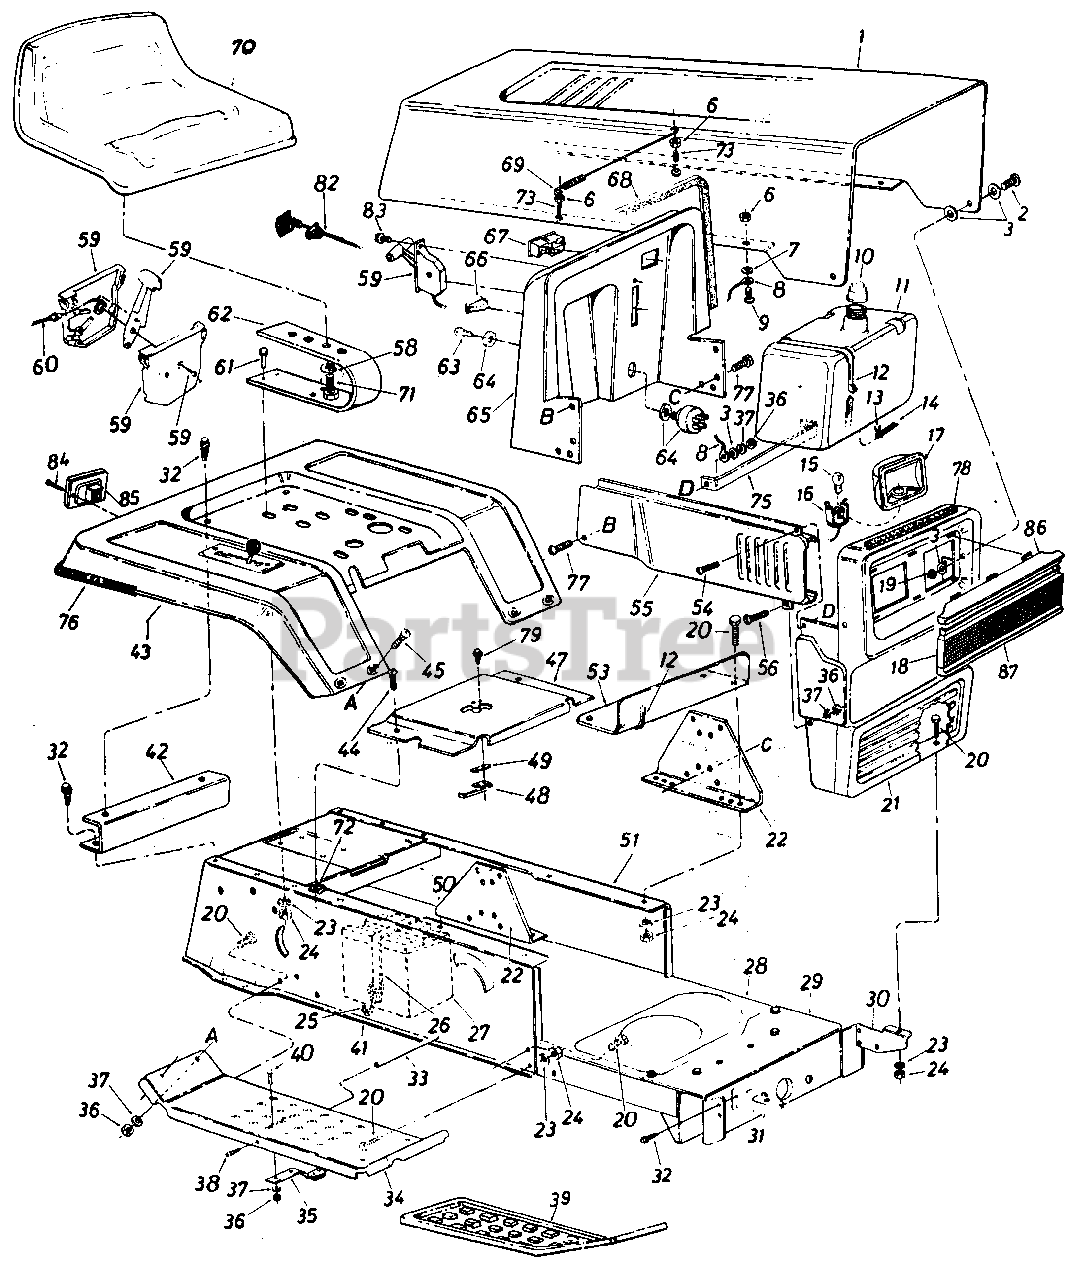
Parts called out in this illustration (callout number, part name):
1	Hood
2	Hex Scr. 1/4-20 x .62" Lg.
3	Fl-Wash. .296" I.D. x .73" O.D.
6	Hex Sems Nut #10-24 Thd.
7	Fl-Wash. .203" I.D. x .41" O.D. x .040
8	Hood Stop
9	Truss Hd. Scr. #10-24 x 1/2"
10	Fuel Cap Gauge
11	Fuel Tank
12	Tie Strap
13	Hose Clamp
14	Fuel Line
15	Lamp
16	Twist Lock Lamp Socket
17	Headlight Housing
18	Headlight Bezel
19	Hex L-Nut 1/4-20 Thd.
20	Hex Bolt 5/16-18 x .75" Lg.
23	L-Wash. 5/16" I.D.
24	Hex Nut 5/16-18 Thd.
25	Battery Strap Hook
26	Battery Hold Down Strap
27	12V Battery
28	Lower Frame
29	Front Pivot Brk't.
30	Grille Mount Brk't. L.H.
33	Running Board Rod
34	Running Board
35	Blade Brake Ass'y.
36	Hex Nut 1/4-20 Thd.
37	L-Wash. 1/4" I.D.
38	Truss Mach. Scr. 5/16-18 x .75" Lg.
39	Foot Pad
40	Carriage Bolt 1/4-20 x .62"
41	R.H. Side Frame
42	Fender Mount Brace
43	Rear Fender
45	Carriage Bolt 1/4-20 x .50"
47	Transmission Panel
48	Reverse Safety Switch
49	Insulator Nut Plate
50	Hitch Plate
51	L.H. Side Frame
53	Fuel Tank Support
54	Truss Hd. Scr. 1/4-20 x .75" Lg.
55	Side Cover R.H.
56	Truss Mach. Scr. 1/4-20 x .50" Lg.
58	L-Wash. 1/2" I.D.
59	Throttle Control Box Ass'y.
60	Throttle Control Wire
61	Hex Bolt 5/16-18 x 1.0"
62	Seat Spring 5.5" High
63	Ignition Key
64	Ignition Switch
65	Dash Panel
66	Light Switch
67	Ammeter
68	Trim Strip 27"
69	Hood Spring
70	Seat Ass'y.
71	Hex Bolt 1/2-13 x 1.0" Lg.
72	Speed Nut #10Z
73	Hex Scr. #10-24 x 1.0" Lg.
75	Tie Strap Grille/Side Panel
76	Trim Strip 81"
77	Hex Wash. Hd. Tap Scr. 1/4 x.75" Lg.
78	Foam Strip 3/8 x 1-1/8" x 11/2" Lg.
79	Hex Wash. Hd. AB-Tap #8 x .50" Lg.
82	Choke Control 29" Lg.
83	Truss Mach. AB-Tap Scr. #10 x .5" Lg.
84	Truss Hd. AB-Tap Scr. #6 x .62" Lg.
85	Taillight
86	Upper Frame For Bezel
87	Lower Frame For Bezel
